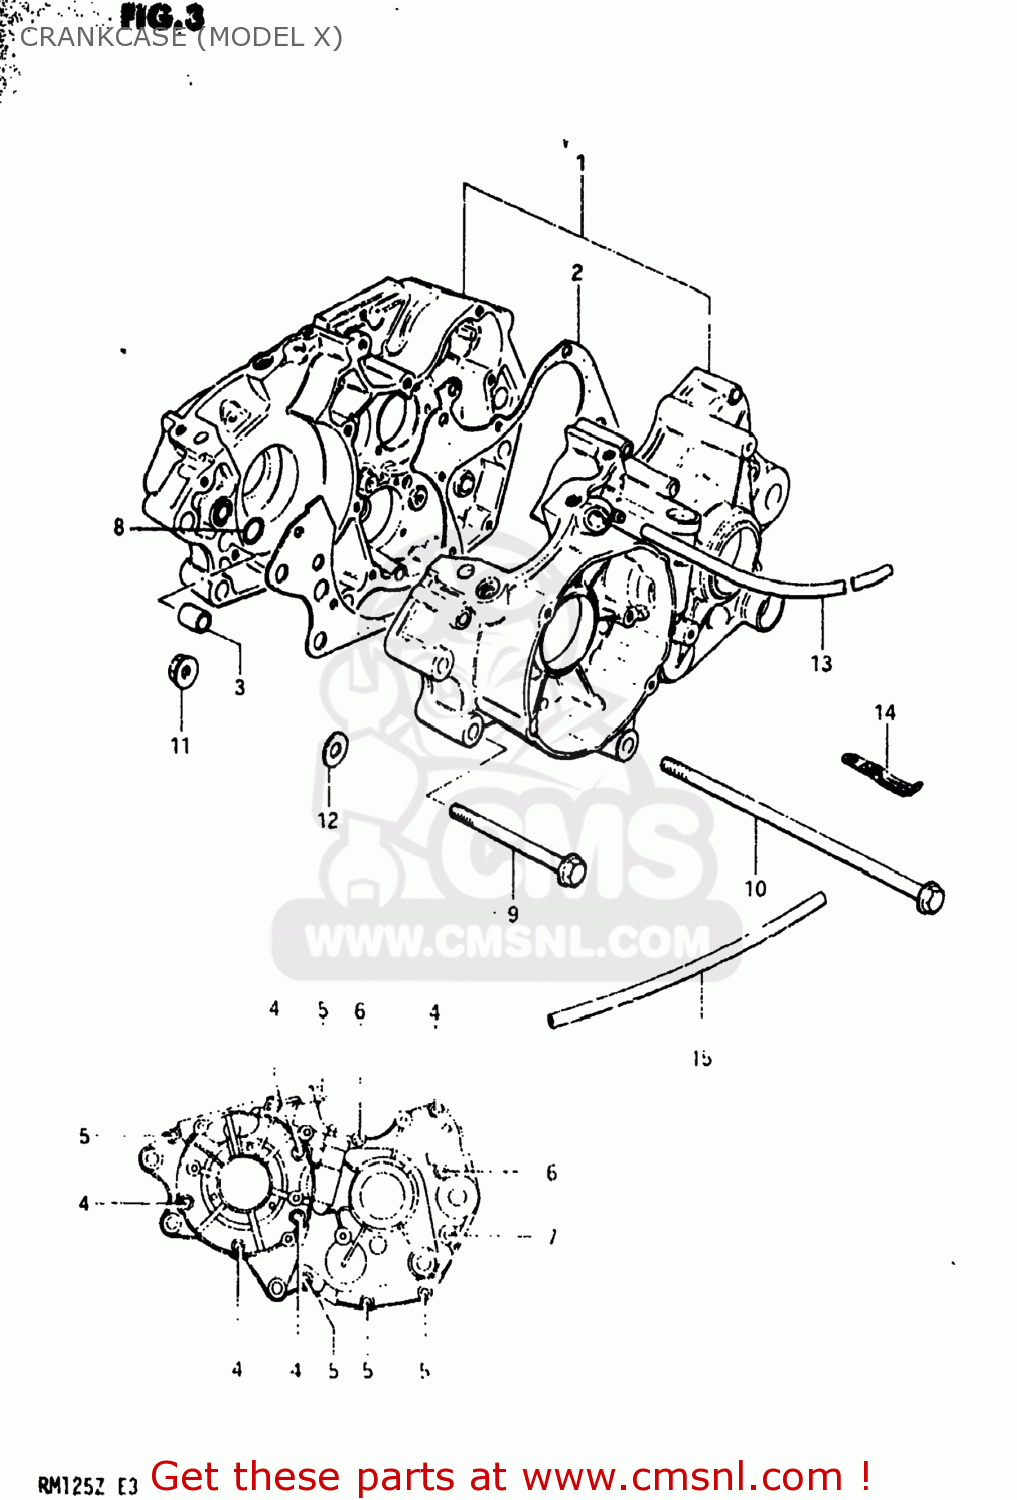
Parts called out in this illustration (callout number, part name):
1	CRANKCASE ASSEMBLY (ASB)
2	GASKET,CRANKCASE (MCA)
3	PIN
4	SCREW (6X45)
5	SCREW
6	SCREW
7	SCREW 6X65
8	O RING(D:1.9,ID:13.8)
9	BOLT
10	BOLT
11	NUT
12	WASHER
13	HOSE
14	CLAMP
15	HOSE
